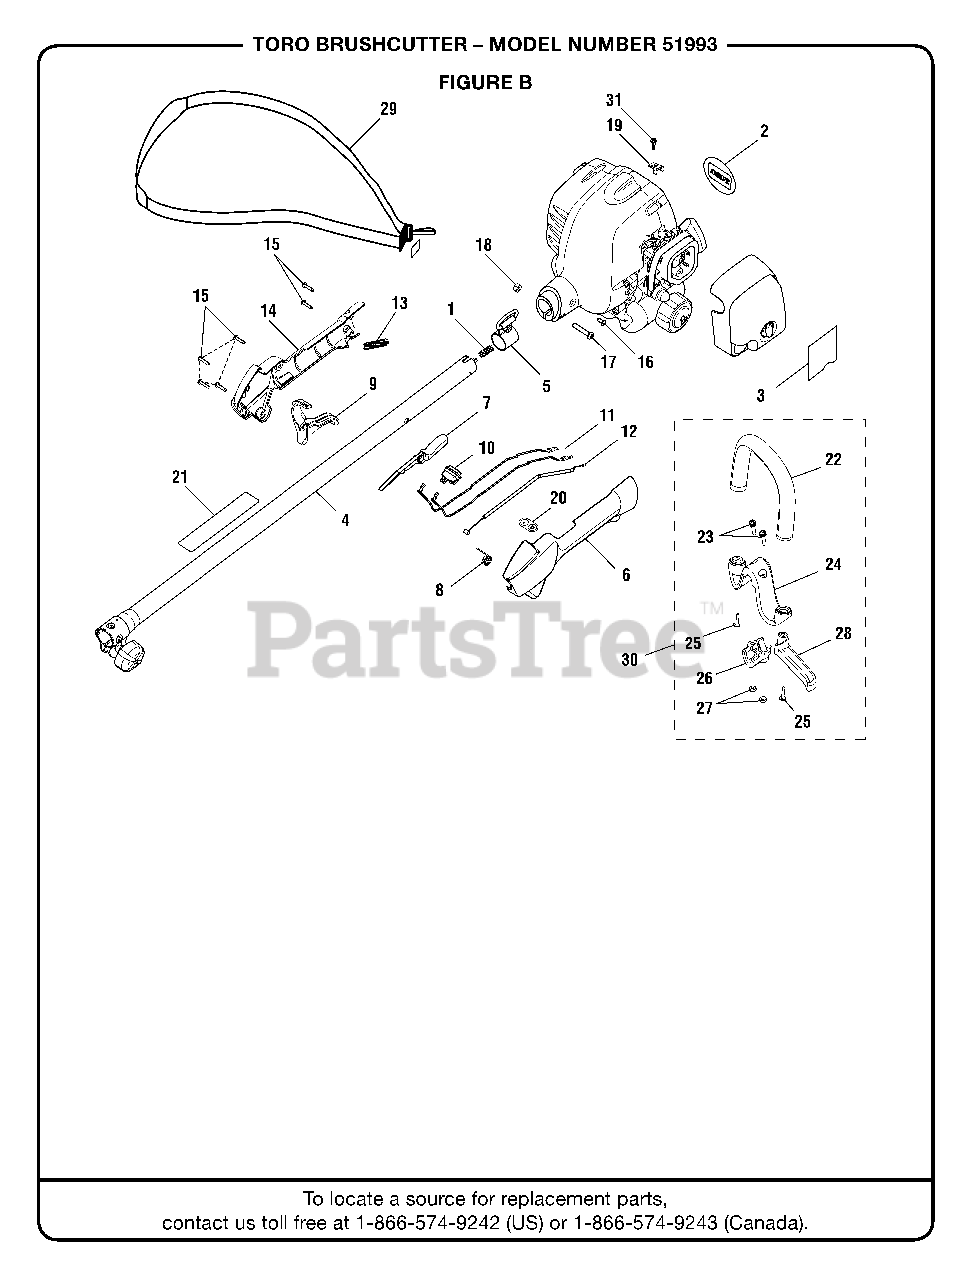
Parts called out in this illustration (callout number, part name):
1	COMPRESSION SPRING
2	LOGO PLATE
3	LOWER START LABEL
4	UPPER SHAFT ASSEMBLY
5	HANGER BRACKET
6	REAR HANDLE SUPPORT
7	LOCK-OFF BUTTON
8	TRIGGER SPRING
9	TRIGGER
10	SWITCH WITH DUST SHIELD
11	LEAD
12	CABLE, THROTTLE
13	CORRUGATED TUBE
14	REAR HANDLE COVER
15	SCREW (M4 X 16 mm)
16	SCREW (#8-16 X 1/2 in. TRI-LOBULAR)
17	SCREW (M6 X 1-30 mm)
19	THROTTLE CABLE CLAMP
20	ON/OFF LABEL
21	WARNING LABEL
22	ASSIST HANDLE W/GRIP
23	SCREW (#12-24 X 1 in.)
25	SLOTTED TORX SCREW
26	CLAMP
27	HEX NUT (12-24)
28	BARRIER BAR
29	HARNESS ASM. W/LABEL
30	ASSIST HANDLE W/BARRIER
31	SCREW (M4 X 16 mm)
